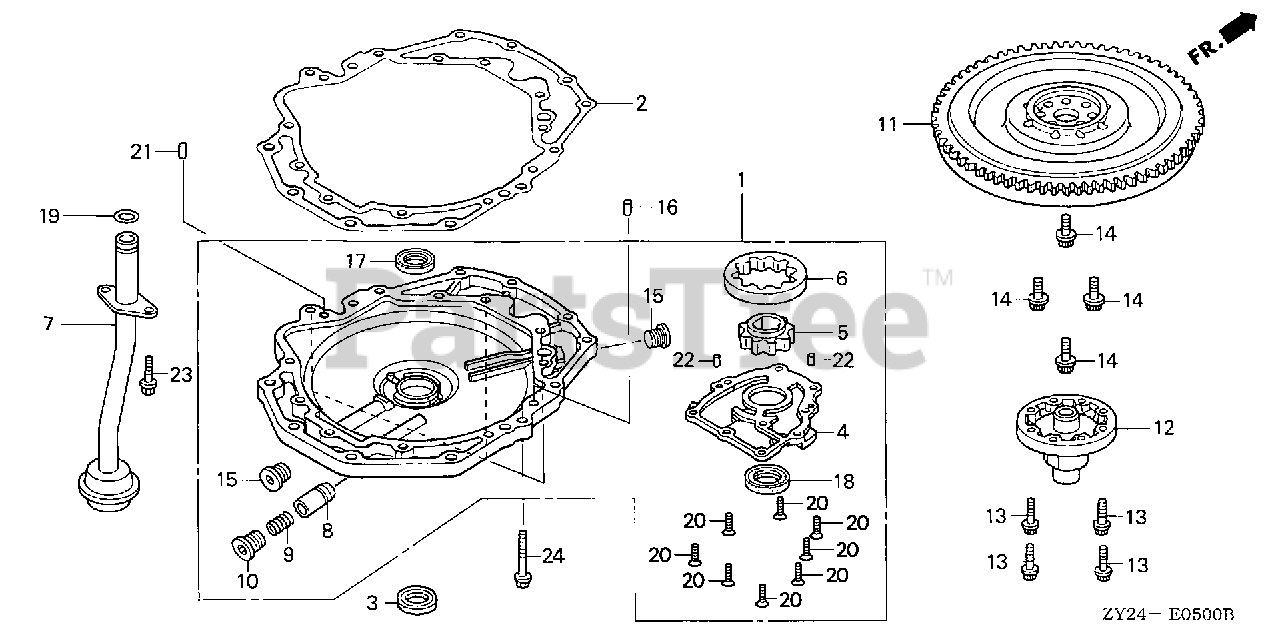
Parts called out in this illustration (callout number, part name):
1	PUMP ASSY., OIL *NH8* (DARK GRAY)
2	GASKET, OIL PUMP BODY
3	RUBBER, OIL PUMP
4	COVER, OIL PUMP
5	ROTOR, OIL PUMP (INNER)
6	ROTOR, OIL PUMP (OUTER)
7	STRAINER, OIL
8	VALVE, RELIEF
9	SPRING, RELIEF VALVE
10	BOLT, SEALING (18MM)
11	FLYWHEEL *TBLACK* (BLACK)
12	BOSS, FLYWHEEL
13	BOLT, SPECIAL (8MM)
14	BOLT, FLANGE (12MM)
15	BOLT, SEALING (22MM)
16	PIN, DOWEL (14X15)
17	OIL SEAL (46X60X9)
18	OIL SEAL (31X46X7) (NOK)
19	O-RING (20.6X2.6)
20	SCREW, FLAT (6X16)
21	PIN B, DOWEL (10X16)
22	PIN, DOWEL (5X8)
23	BOLT, FLANGE (6X18)
24	BOLT, FLANGE (8X30)
